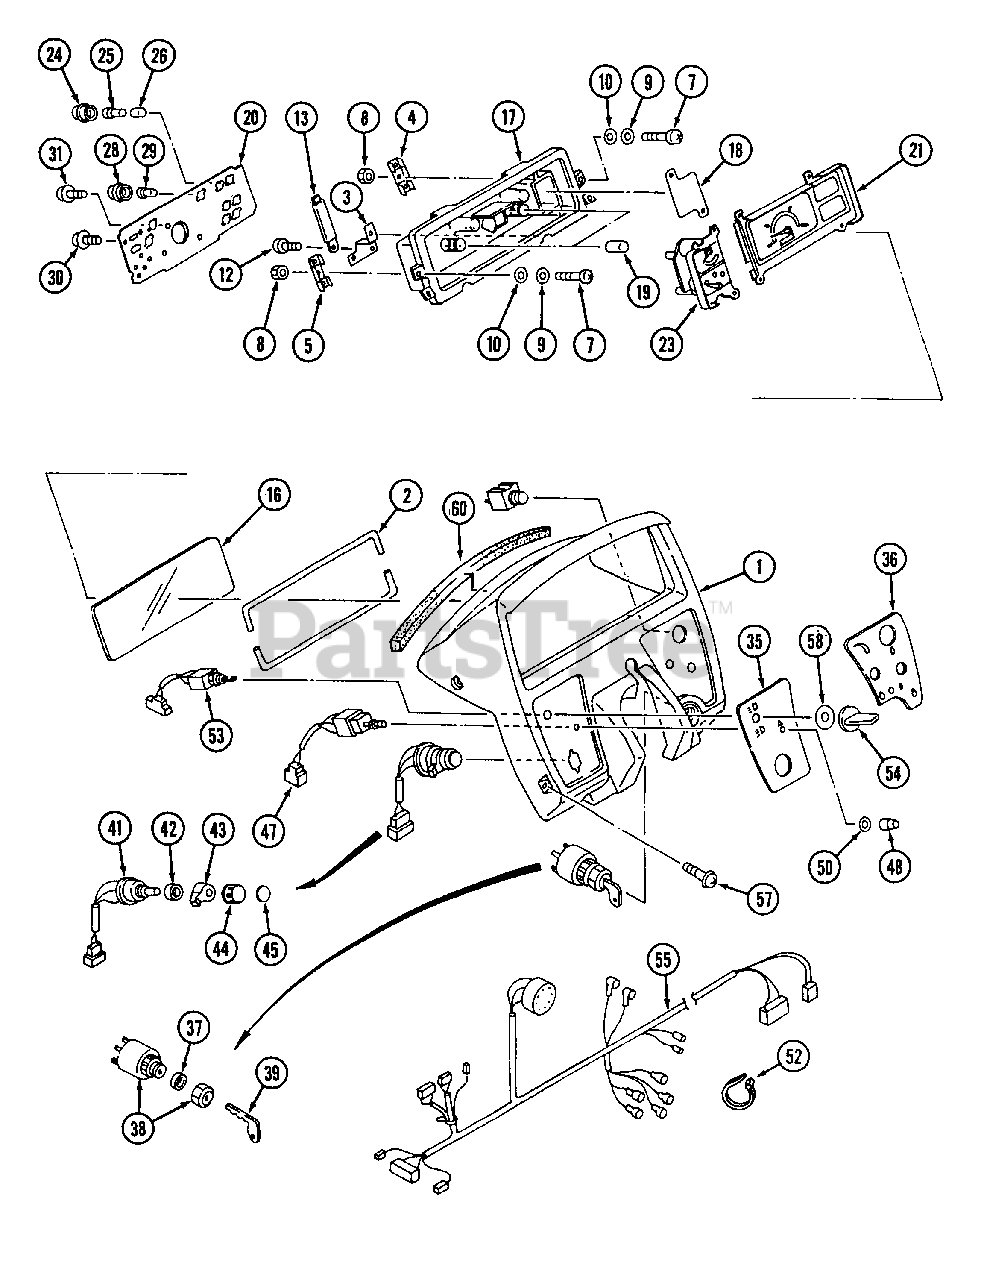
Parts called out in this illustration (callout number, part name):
16	Glass Ass'y.
18	Plate Monitor
19	Lens Indicator
23	Meter Fuel & Temp.
35	Label, Panel L.H.
36	Label, Panel R.H.
37	Packing Starter
38	Switch Starter
39	Key, Starter
41	Switchbody Ass'y.
42	Ring Nut
43	Flasher Lever
44	Lighting Knob
48	Switch, Cover
53	Switch, Light H/L
58	Packing Rubber
